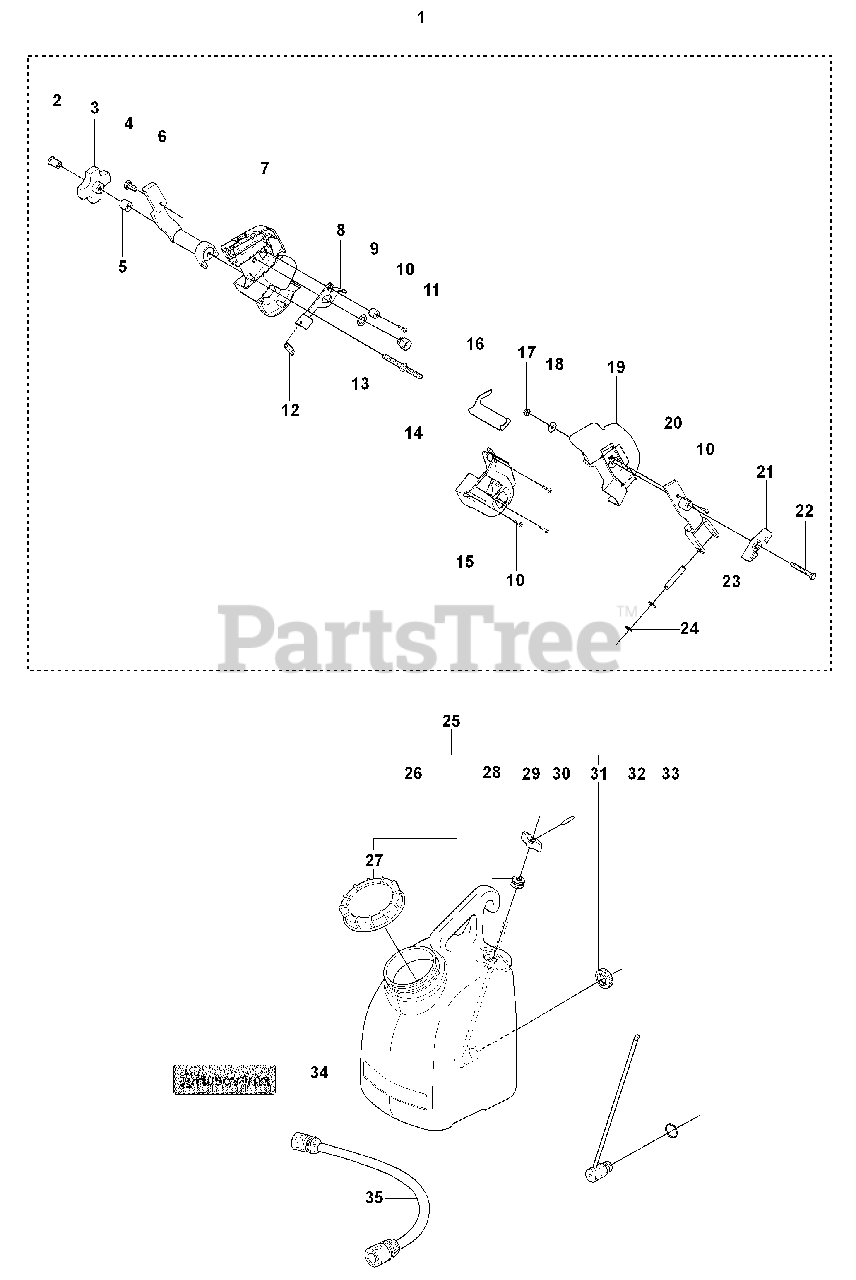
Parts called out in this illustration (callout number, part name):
1	HOLDER ASSY
3	KNOB
4	SCREW
5	SPACING SLEEVE
18	WASHER
24	RETAINING RING
25	WATER TANK
26	WATER TANK
28	ANTIVIBE ELEMENT
35	HOSE
